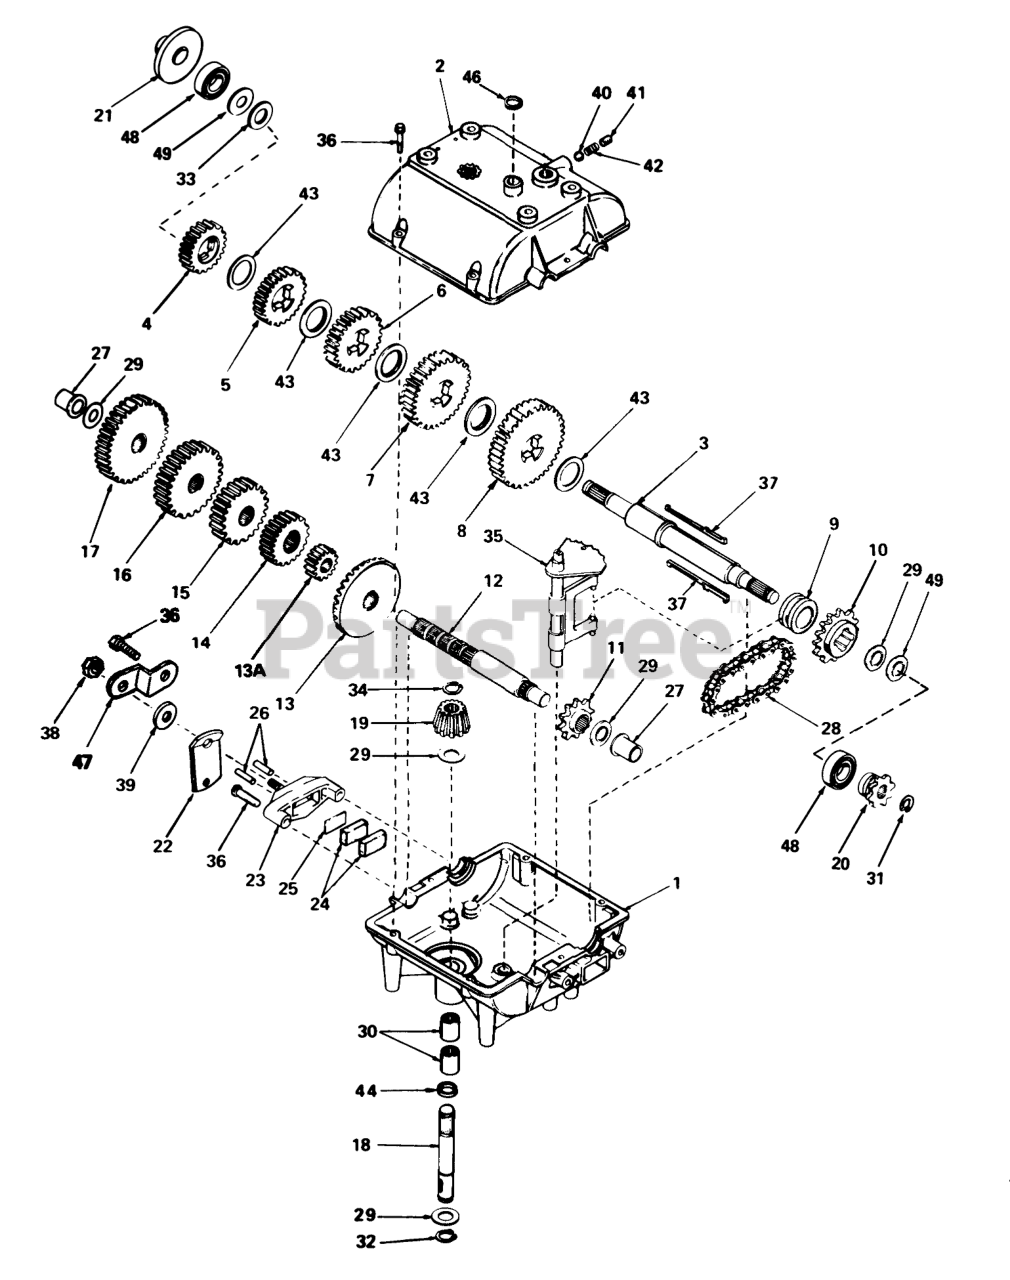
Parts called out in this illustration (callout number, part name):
1	Case-Transmission
2	Cover-Transmission
3	Shaft, Output
4	Gear, Spur (19 teeth)
5	Gear-Spur (22 teeth)
6	Gear-Spur, 25 Teeth
7	Gear-Spur, 30 Teeth
8	Gear-Spur, 35 Teeth
9	Collar-Shift
10	Sprocket-18 Teeth
11	Sprocket-9 Teeth
12	Countershaft
13	Gear-Bevel (42Teeth)
13A	Gear-Spur 15 Teeth
14	Gear-Spur, 20 Teeth
15	Gear-Spur, 25 Teeth
16	Gear-Spur (28 teeth)
17	Gear, Spur (31 Teeth)
18	Shaft-Input
19	Bevel Pinion-Input
20	Sprocket (8 teeth)
22	Lever, Brake
23	Nozzle-Carburetor
24	Brake Pad
25	Brake Pad Plate
26	Dowel Pin
27	Bushing-Flange
28	Chain-Roller #41
29	Washer
30	Bearing-Needle
31	Piston Asm (.020 O S)
32	Ring-Snap
33	Washer
34	Ring-Retainer
35	Rod and Fork ASM
36	Ring Set (.020 O S)
38	Locknut
39	Washer
40	Ball-Steel
41	Screw-Set
42	Spring
43	Washer
44	O Ring
46	Cut Seal-Square
47	Bracket
48	Bearing-Ball
49	Thrust Washer
